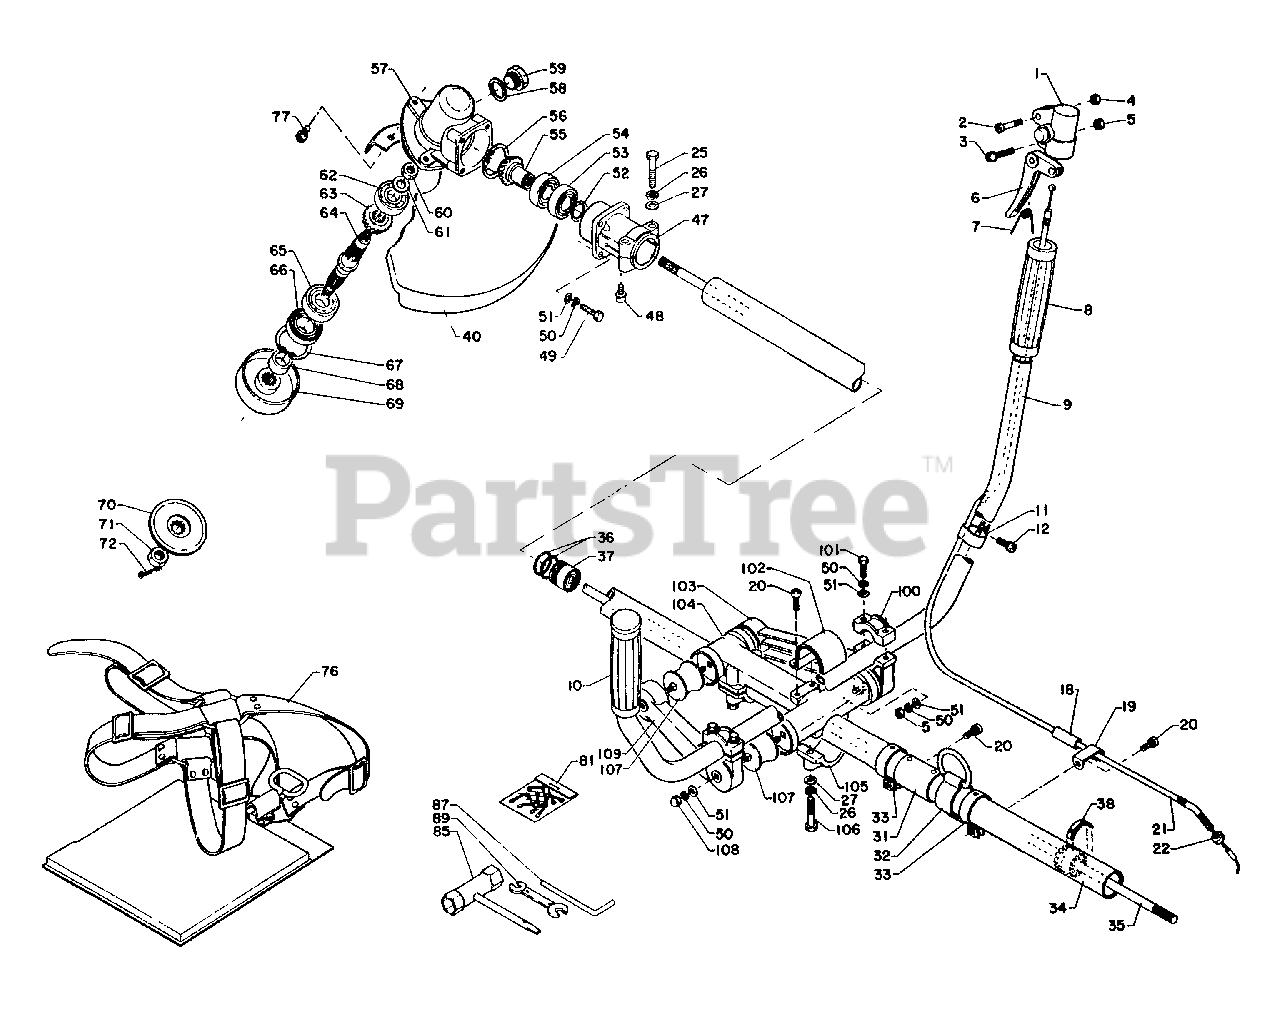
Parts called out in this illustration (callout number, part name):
1	BRACKET, TRIGGER
2	SCREW - 5X30
3	SCREW - 5X25
4	LOCKNUT - 5
6	TRIGGER, THROTTLE
7	SPRING, TRIGGER
8	GRIP, HANDLE
9	HANDLE
10	GRIP, HANDLE - LEFT
11	CLAMP
12	SCREW - 5X10
20	SCREW - 5X14
21	CABLE, THROTTLE
25	BOLT - 6X32
26	LOCKWASHER - 6
27	WASHER - 6
31	COLLAR
32	HOOK
33	HOOK
34	MAIN PIPE ASSY
35	DRIVESHAFT - SOLID
37	STOPPER
38	LABEL - ALIGNMENT
40	SHIELD, DEBRIS
47	CASE, GEAR
48	SCREW - 5X12
49	BOLT - 5X20
50	LOCKWASHER - 5
51	WASHER - 5
52	RING, RETAINING - 15
53	BEARING, BALL - 6002D
54	BEARING, BALL - 6002
55	GEAR SET
56	RING, RETAINING - 32
57	CASE, GEAR
58	CASE, GEAR
59	FITTING, GREASE
61	WASHER - 8
62	BEARING, BALL - 6201
64	GEAR - SHAFT
65	BEARING, BALL - 6202
66	SEAL, OIL
67	RING, RETAINING - 35
69	ADAPTOR, BLADE - UPPER
70	ADAPTOR, BLADE - LOWER
71	NUT - 10 -- LEFT HAND
72	PIN, SPLIT - 2X22
76	SHOULDER STRAP ASSY
77	SCREW - 5X14
78	ADAPTOR
81	PIN, SPLIT - 2X22
85	T-WRENCH
87	LOCKING TOOL
89	SPANNER - 8X10mm
100	RETAINER
101	BOLT - 5X25
102	PLATE
103	ARM, RETAINER - RIGHT
104	Holder, d.s. housing
105	HOLDER
106	BOLT - 6X30
107	CUSHION
108	NUT - 5 -- CAP
109	ARM, HANDLE - LEFT
